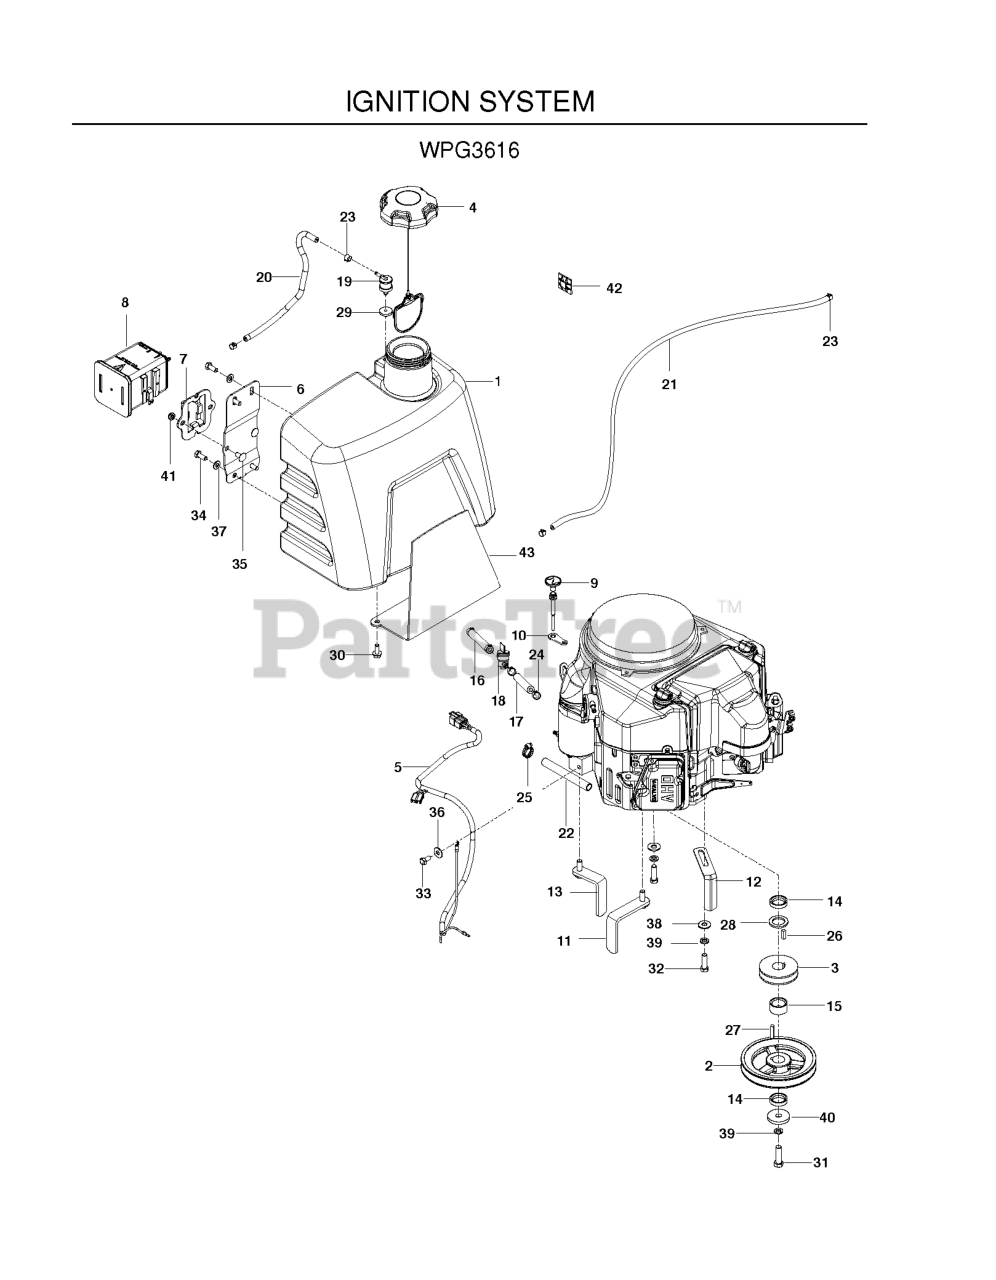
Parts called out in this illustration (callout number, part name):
1	TANK, FUEL BLK
2	PULLEY, ENGINE
4	CAP, FUEL
5	LOWER HARNESS
6	MOUNT, CANISTER BLK
7	BRACKET, CANISTER
8	CANNISTER, CARBON
9	CABLE, CHOKE
10	SUPPORT, CHOKE BLK
11	BELT GUIDE - LONG
12	BELT GUIDE
13	BELT GUIDE, SHORT
16	FUEL LINE 5"
17	FUEL HOSE 3.5
18	FUEL VALVE
19	VALVE.FUEL.CHECK
20	HOSE, 3/16" VAPOR, 13"
21	HOSE, VAPOR 3/16 X 48"
22	HOSE, OIL DRAIN, 5"
23	CLAMP, HOSE
24	HOSE CLAMP
25	HOSE CLAMP T-1865
26	KEY 1/4 SQ X 3/4
27	KEY 1/4 SQ X 1 1/8
28	BUSHING, 10GA MACHINERY
29	GROMMET, CHECK VALVE
30	HHFS 5/16-18 X 3/4
31	HCS 7/16F X 1 1/2
32	HCS 3/8C X 1 1/4 GR5
33	HCS M8-1.25 X 16MM GR 5 ZD
34	SCREW 5/16C X 1 HEX CAP
35	CARRIAGE BOLT 5/16C X 5/8"
36	WASHER 5/16 FLAT
37	FLAT WASHER 5/16 SAE
38	WASHER 3/8 FLAT
39	SLW 3/8 STD
40	SPINDLE WASHER
41	5/16-18 THIN PROF NY
42	MOUNTING BLOCK CABLE TIE
43	PLATE ID, ORANGE
